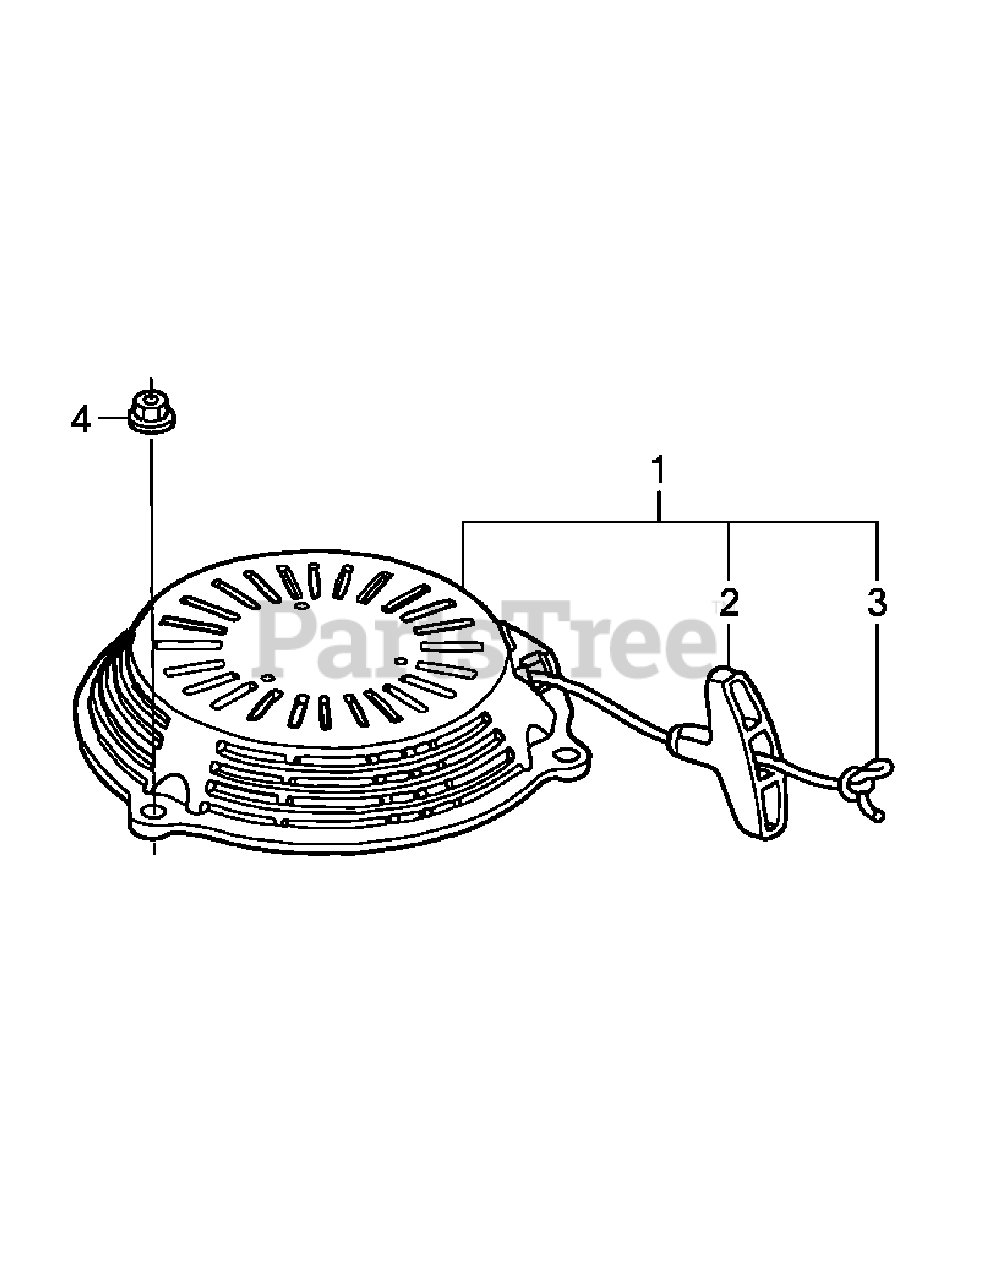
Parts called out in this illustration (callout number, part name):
1	Recoil Starter Assembly
2	Starter Grip
3	Recoil Starter Rope
4	Flange Nut, 6mm
